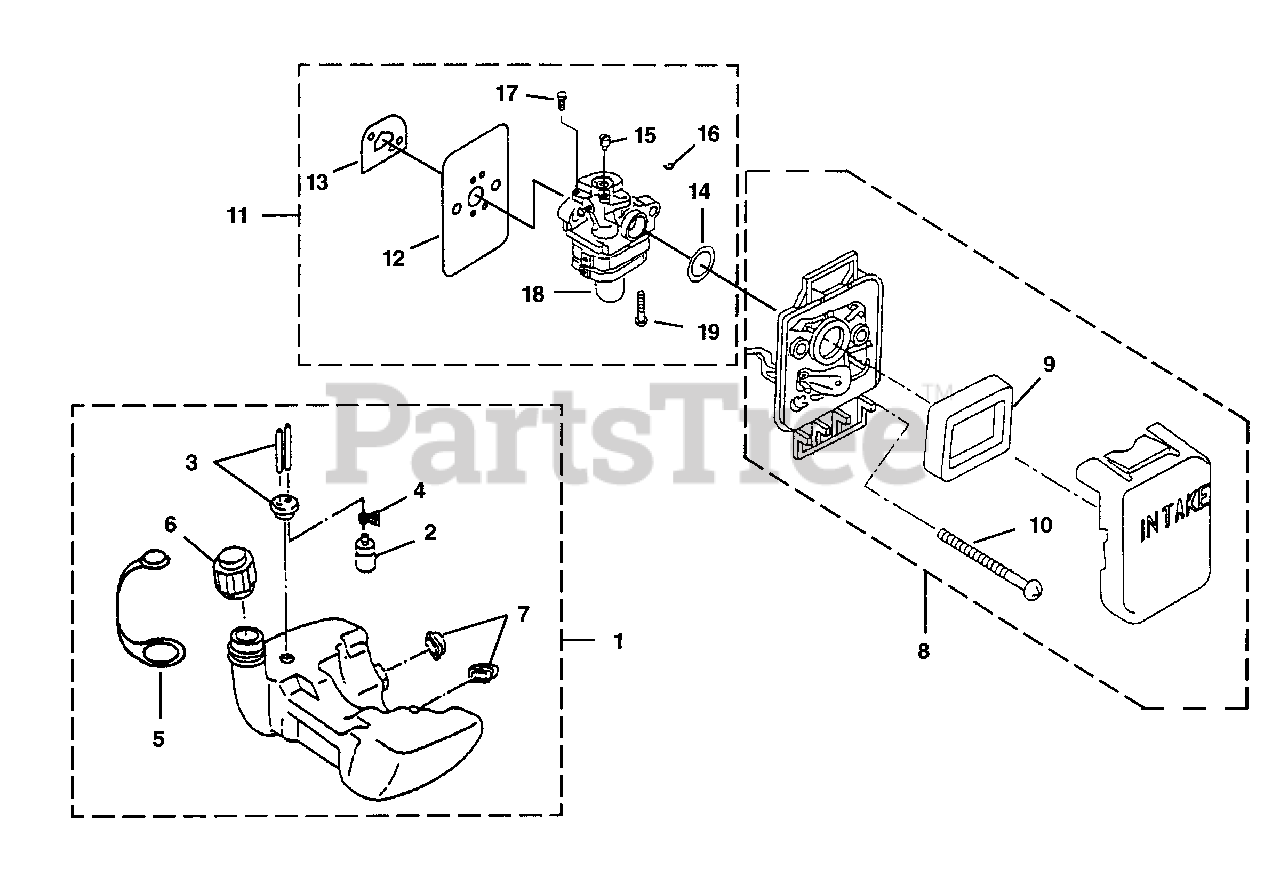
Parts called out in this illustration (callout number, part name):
1	FUEL TANK ASSEMBLY
2	FILTER-Fuel
4	CLAMP-Hose
5	CAP-Retainer
6	CAP-Fuel
7	RUBBER BUMPER KIT
8	AIR FILTER ASSEMBLY
9	FILTER-Air
10	SCREW ASSEMBLY (M5 x 14)
11	CARBURETOR ASSEMBLY
12	GASKET-Carburetor
13	GASKET-Heat Dam
14	RING-Packing
15	SWIVEL-Throttle Cable
18	PUMP-Primer
19	SCREW-Primer Cover
